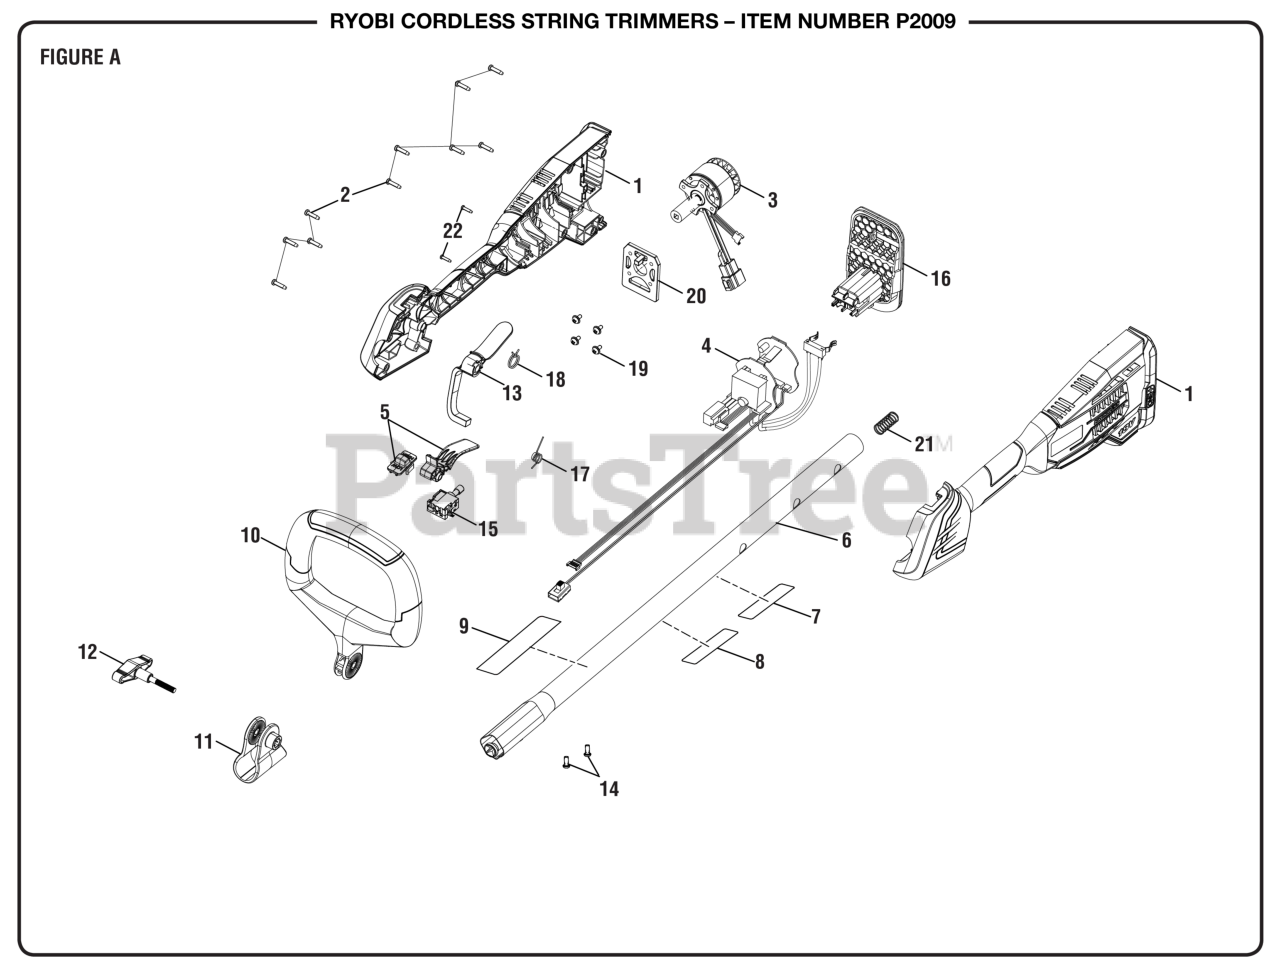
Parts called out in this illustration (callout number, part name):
1	Rear Handle Assembly
2	Screw (M4 x 16 mm, T15 Torx Pan Hd.)
3	Motor Assembly
4	Electric Controller and Switch Assembly
5	Trigger Assembly
6	Upper Boom Assembly
7	Warning Label (Upper End)
8	Data Label
9	Warning Icon Label
10	Lower Auxiliary Handle
11	Handle Bracket Assembly
12	Knob Assembly
13	Lock-Off Trigger
14	Screw w/Lock Washer (M5 x 8 mm, Pan Hd.)
15	Variable Speed Switch
16	Battery Foot
17	Torsion Spring
18	Torsion Spring
19	Screw w/Washer (M4 x 8 mm)
20	Motor Plate
21	Compression Spring
22	Screw (M3 x 8 mm, Pan Hd., Pan Hd)
